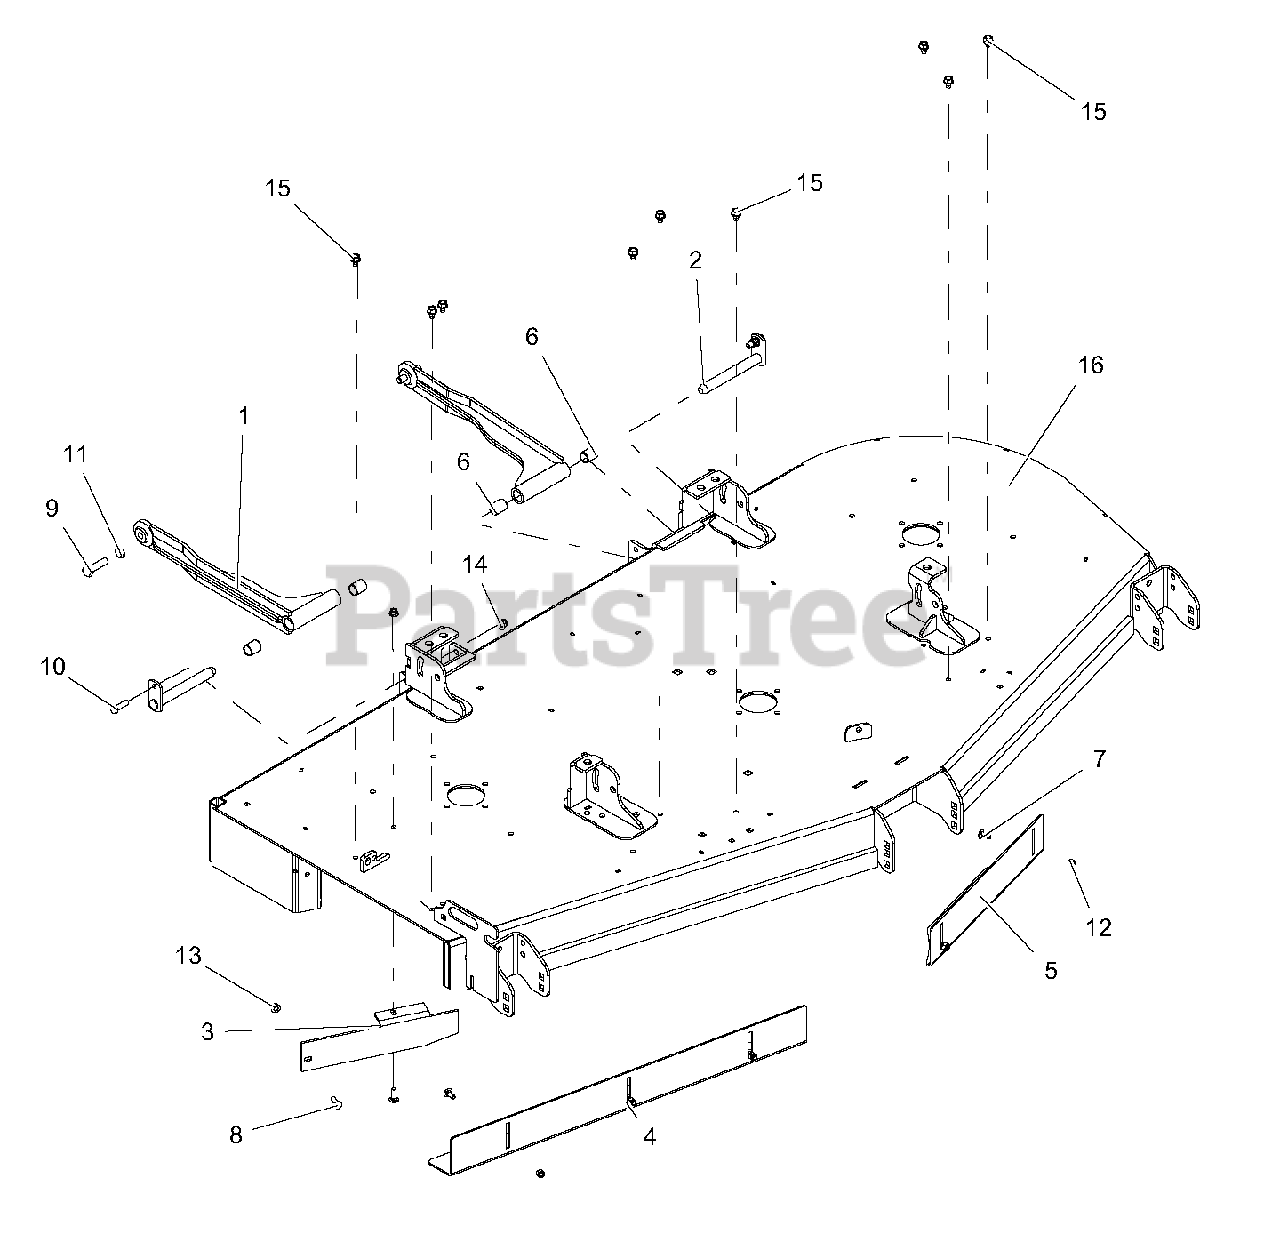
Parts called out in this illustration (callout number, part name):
1	DECK STABILIZER ARM W/BUSHINGS
2	WLDMT, MOWER MTG. PIN
3	BAFFLE, 72" DISCHARGE-RED
4	BAFFLE, 72" RH VACUUM-BLACK
5	BAFFLE, 72" LH VACUUM-BLACK
6	BRG, .75 X .875 X 1.00
7	@BLT-RDHDSQNK .31-18X.75 G5 YWZC
8	@BLT-RDHDSQSHNK .31-18X1.00 G5 Y
9	BLT-HEX .50-13X1.75 GR5 YWZC EP80
10	BLT-HEX .38-16X1.25 GR5 YWZC
11	@WSHR-LK .50X.125 REG YWZC
12	@NUT-LK-NYL .312-18 YWZC
13	NUT-LK-NYL-FLG .31-18 YWZC
14	NUT-LK-NYL-FLG .38-16 YWZC
15	SCR-TAP .38-16X.50 HWH TR YWZ
16	72" SIDE DISCH DECK W/SAFETY DECALS
